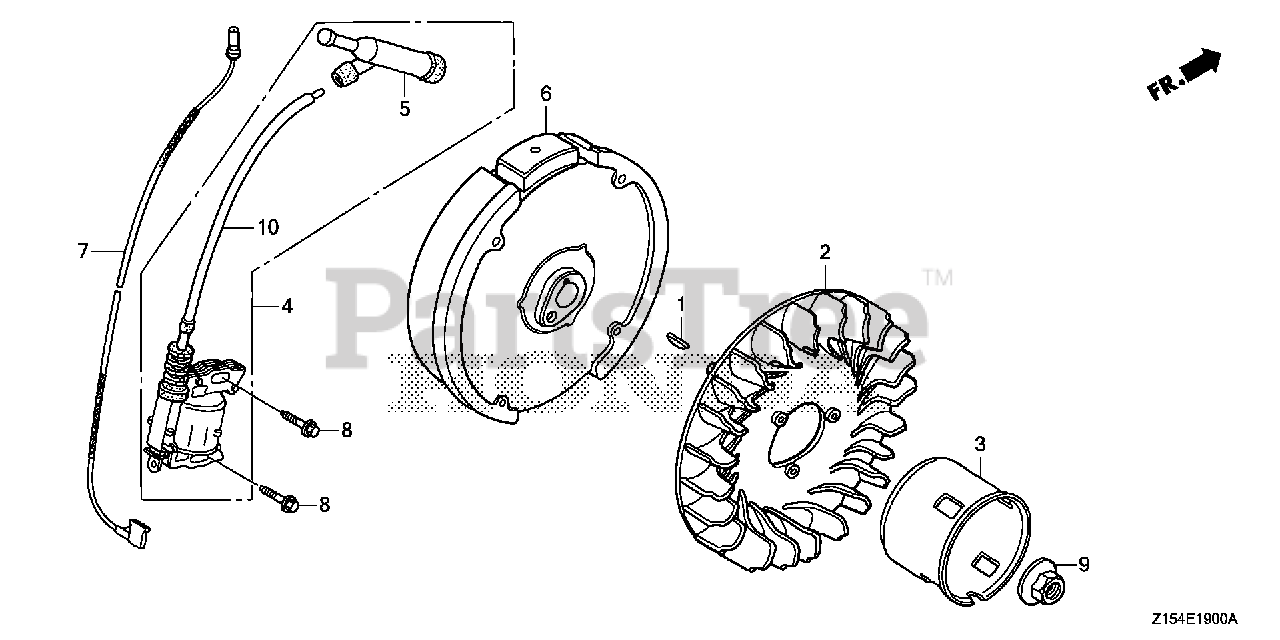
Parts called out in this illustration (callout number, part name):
1	KEY, SPECIAL WOODRUFF (25X18)
2	FAN, COOLING
3	PULLEY, STARTER
4	COIL ASSY., IGNITION (TEC)
5	CAP ASSY., NOISE SUPPRESSOR (TEC)
7	WIRE, STOP SWITCH
8	BOLT, FLANGE (6X25) (CT200)
9	NUT, SPECIAL (14MM)
